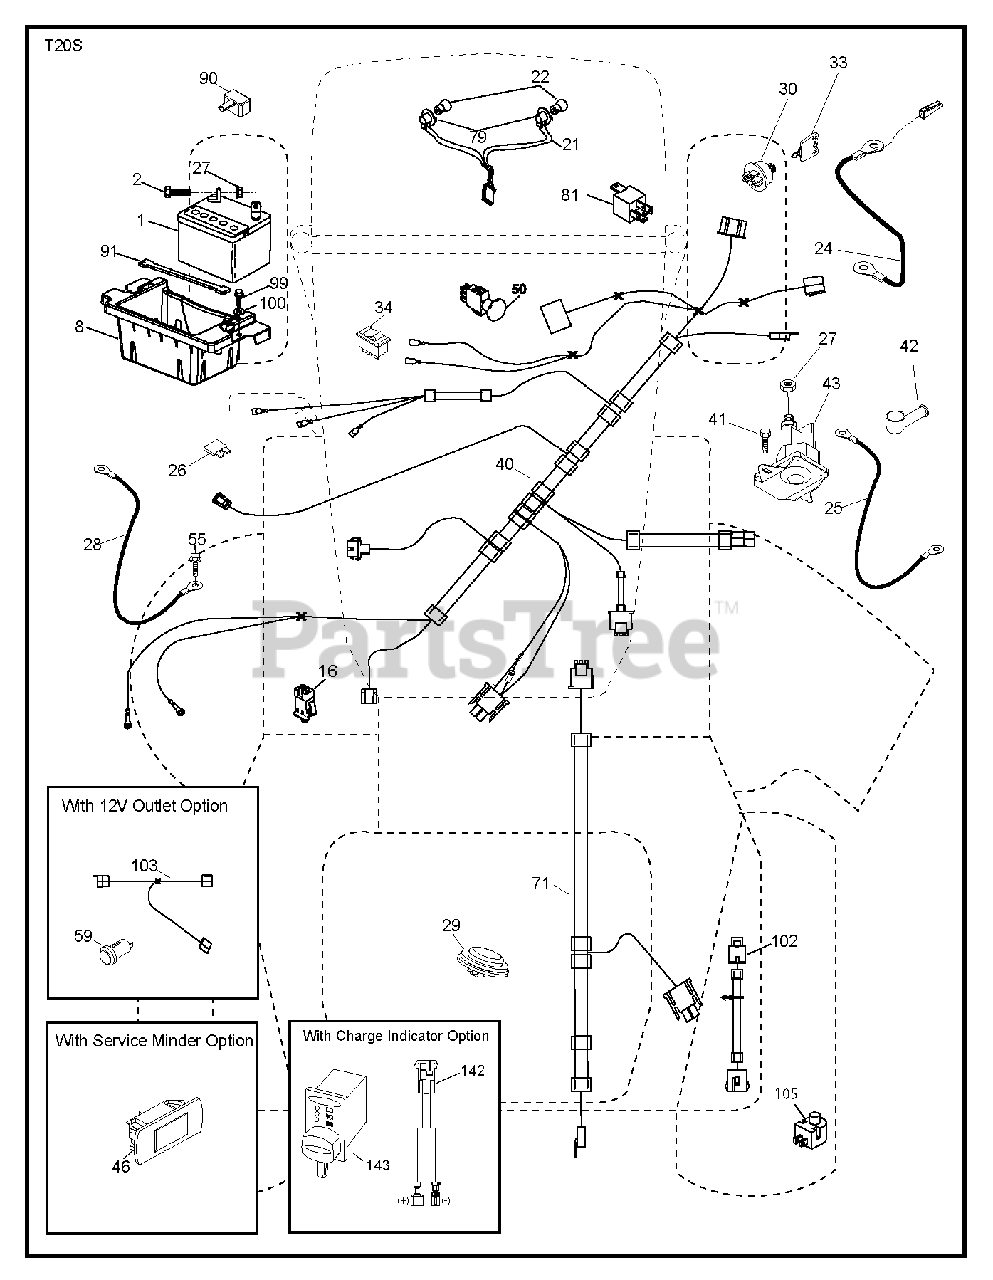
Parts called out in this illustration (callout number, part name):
1	Battery, Dry 30 Amp
2	BOLT.HEX.1/4.X.3/4.DICHROMATE
8	BOX.BATTERY.MOUNT.FRONT.LT
16	SWITCH INTERLOOK PUSH-IN
21	HARNESS.LIGHT W/4152J BULBS
24	CABLE.BATT.POS.WIRE.TG.DA SOL
25	CABLE.STARTER.6G.BL/RED.17.5
26	FUSE 20AMP
27	NUT
28	CABLE GROUND 6 GA 21" 90T BLK
29	SWITCH.SEAT.DELTA.OPC.
30	SWITCH.IGN.DELTA.W.LGH.ROS
33	KEY.CHAIN.BLISTER.PACK.GEN.INT
40	HARNESS.IGN.ELEC.RELAY.TEX.46"
41	SCREW
42	TERMINAL COVER
43	SOLENOID.W/BRASS.PLUNGER
46	RP GUAGE.SRVCMNDR.HRMTR.
50	RB PTO.SWITCH.8 TERMINAL.BLACK
55	SCREW 5/16"
71	HARNESS-CHASSIS SUB
79	BULB HOLDER ASM.
81	RELAY HARNESS.SEALED
90	COVER.TERMINAL.BATTERY
91	STRAP.BATTERY.MOUNT.FRONT(2 2)
99	SCREW HEXWSHR 1/4-20X3/4
102	HARNESS PIGTAIL PCH TEX ROS
105	REVERSE SWITCH
142	RP HARNESS.JUMPER.CTEK
